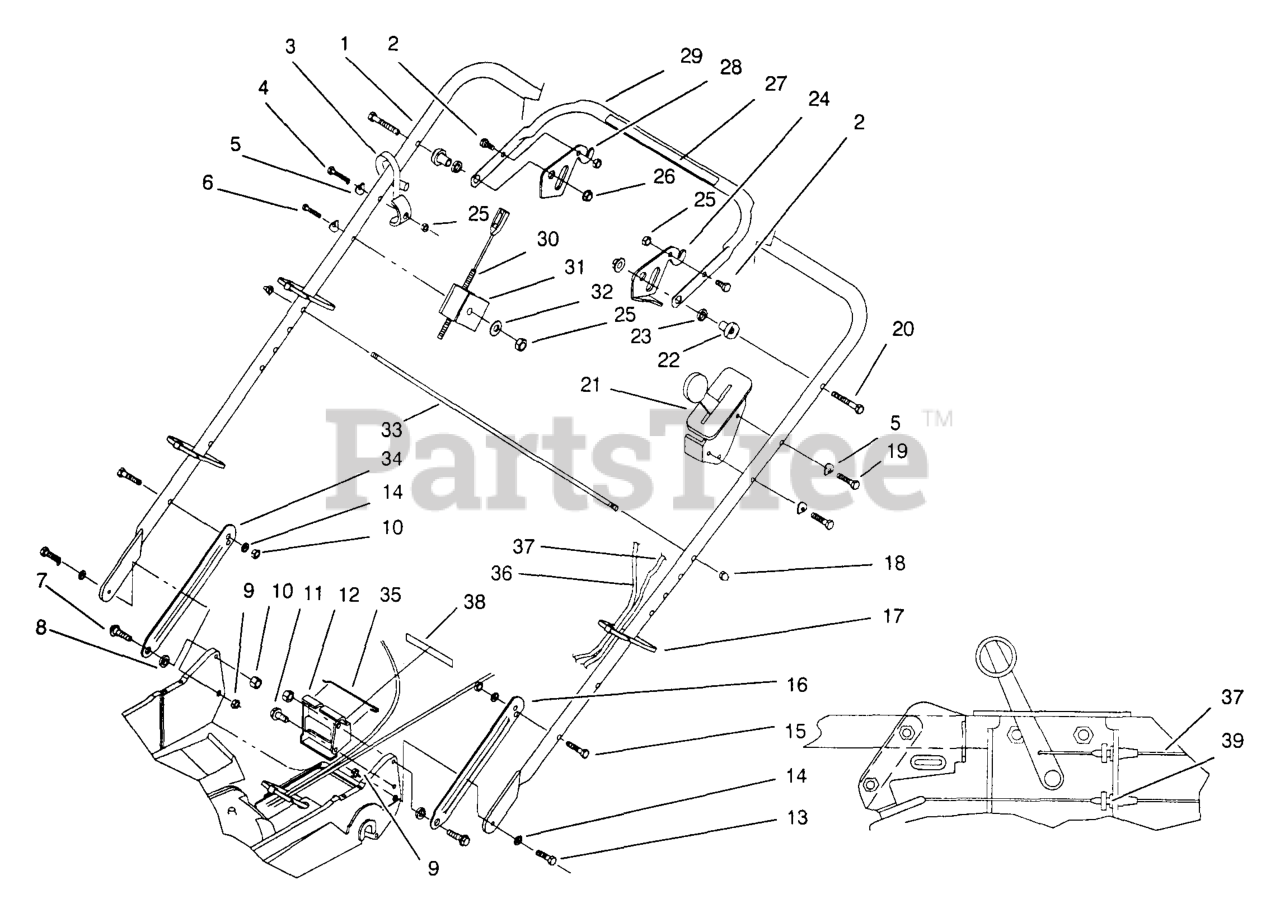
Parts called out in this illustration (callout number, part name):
2	SCREW-HH
3	GUIDE-ROPE
4	SCREW-HH
5	WASHER
6	SCREW-HH
7	SCREW-SHOULDER
8	SPACER
9	NUT-LOCK, NI
10	NUT-LOCK, NI
11	Screw-HWH 5/16-18 X 3/4 Tf
12	BRACKET-ADJUSTMENT, TRACT
13	SCREW-HH
14	WASHER-BELLEVILLE
15	SCREW-HH
17	TIE-CABLE
18	NUT-CAP
19	SCREW-HH
20	SCREW-HH
21	BRACKET-CONTROL, THROTTLE
22	SPACER-SUPPORT
23	SPACER-NYLON
24	LEVER-CONTROL
25	NUT-LOCK, NI
26	NUT-LOCK, NI
28	LEVER-CONTROL
29	BAR-CONTROL
30	CABLE-BRAKE
31	SUPPORT-CABLE
32	WASHER-FLAT
33	ROD-SUPPORT, BAG
35	RETAINER-CABLE
36	CABLE-TRACTION
38	DECAL-POSITION, GEAR
